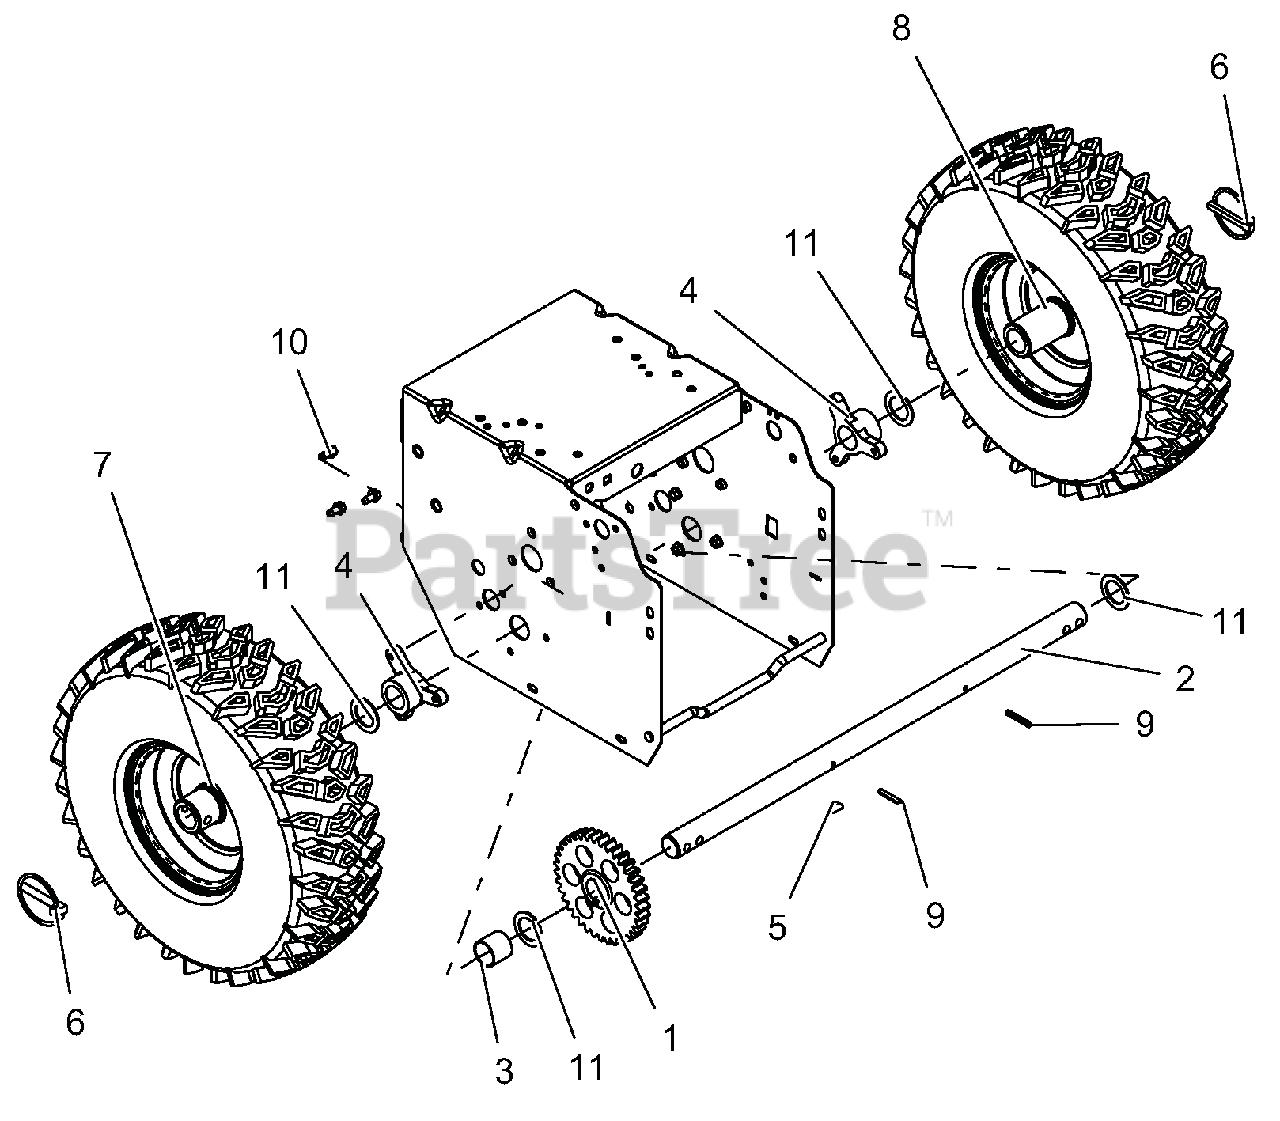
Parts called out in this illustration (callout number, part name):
1	GEAR, SPUR
2	AXLE, 1.00" SOLID
3	BSHG-SLV, 1.012X1.125X1.00
4	BUSHING, AXLE
5	KEY-WDRF .25X.750X.313 SAE91
6	PIN-LOK .31X2.00
7	TIRE/WHEEL, RH 15X5.00-6 PIN
8	TIRE/WHEEL, LH 15X5.00-6 PIN
9	PIN-ROLL .188X1.25
10	SCR-TAP .25-20X.50 HWH TR YWZ
11	WSHR-FL-STL 1.010X1.505X.062YZ
